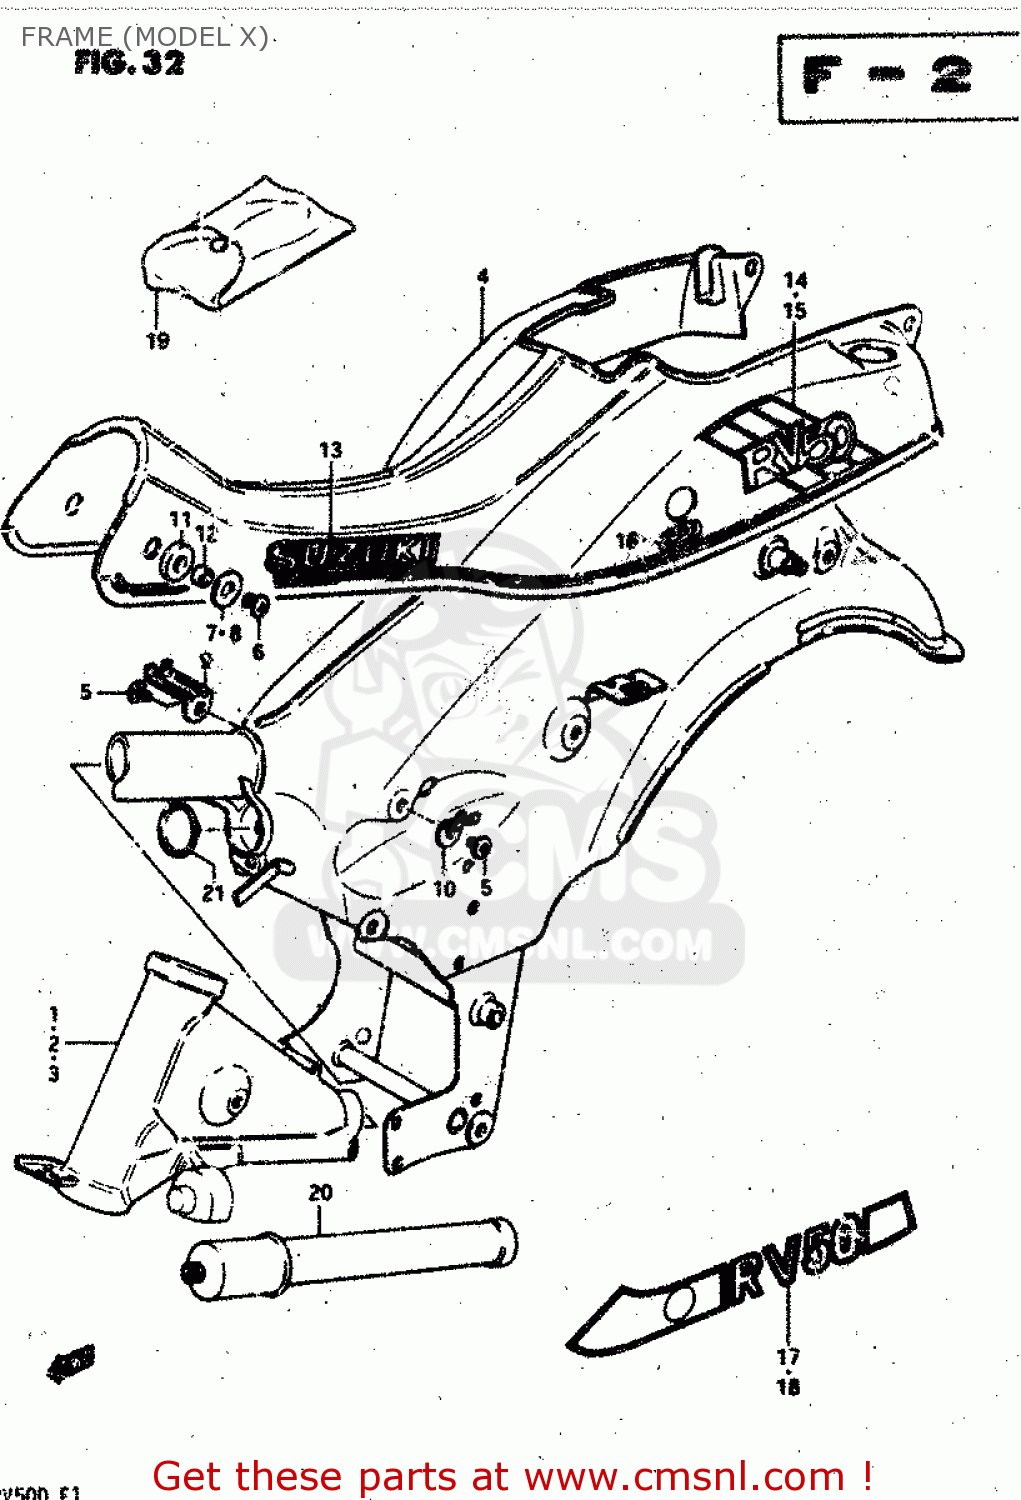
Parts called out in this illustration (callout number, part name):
1	FRAME (BLUE)
2	FRAME (BLUE)
3	FRAME (BLUE)
4	COVER, FRAME (WHITE)
5	SCREW
6	SCREW
7	WASHER
8	WASHER
9	BRACE, FRAME COVER RH
10	BRACE, FRAME COVER LH
11	CUSHION
12	SPACER(8.1X11X5.4)
13	EMBLEM
14	TAPE, RH
15	TAPE, LH
16	EMBLEM,CCIS
17	TAPE, RH
18	TAPE, LH
19	TOOL ASSY
20	INFLATOR, AIR
21	CUSHION
